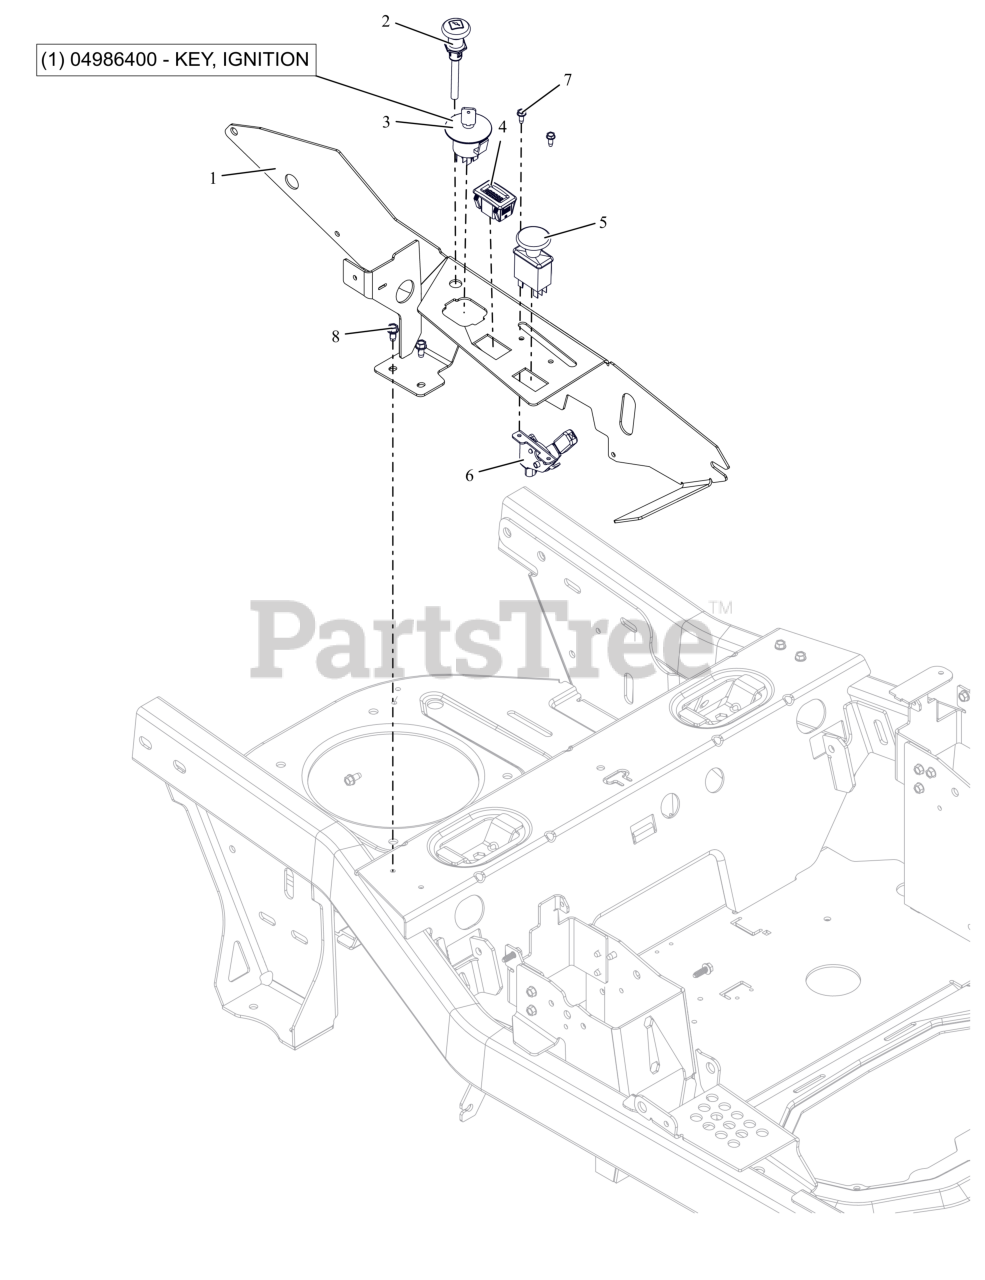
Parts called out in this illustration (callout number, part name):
1	PANEL- CONTROL-RH-GRAVELY
2	CABLE- CHOKE-SNAP IN 37"
3	KEYSWITCH-IGNITION 4 POS
3	KEY, IGNITION
4	HOUR METER
5	SWITCH, CLUTCH
6	CABLE- THROTTLE
7	SCR,TAP #10-24X.50 HWH TR ZCC
8	SCR-TAP .25-20X.50 HWH ZCC
